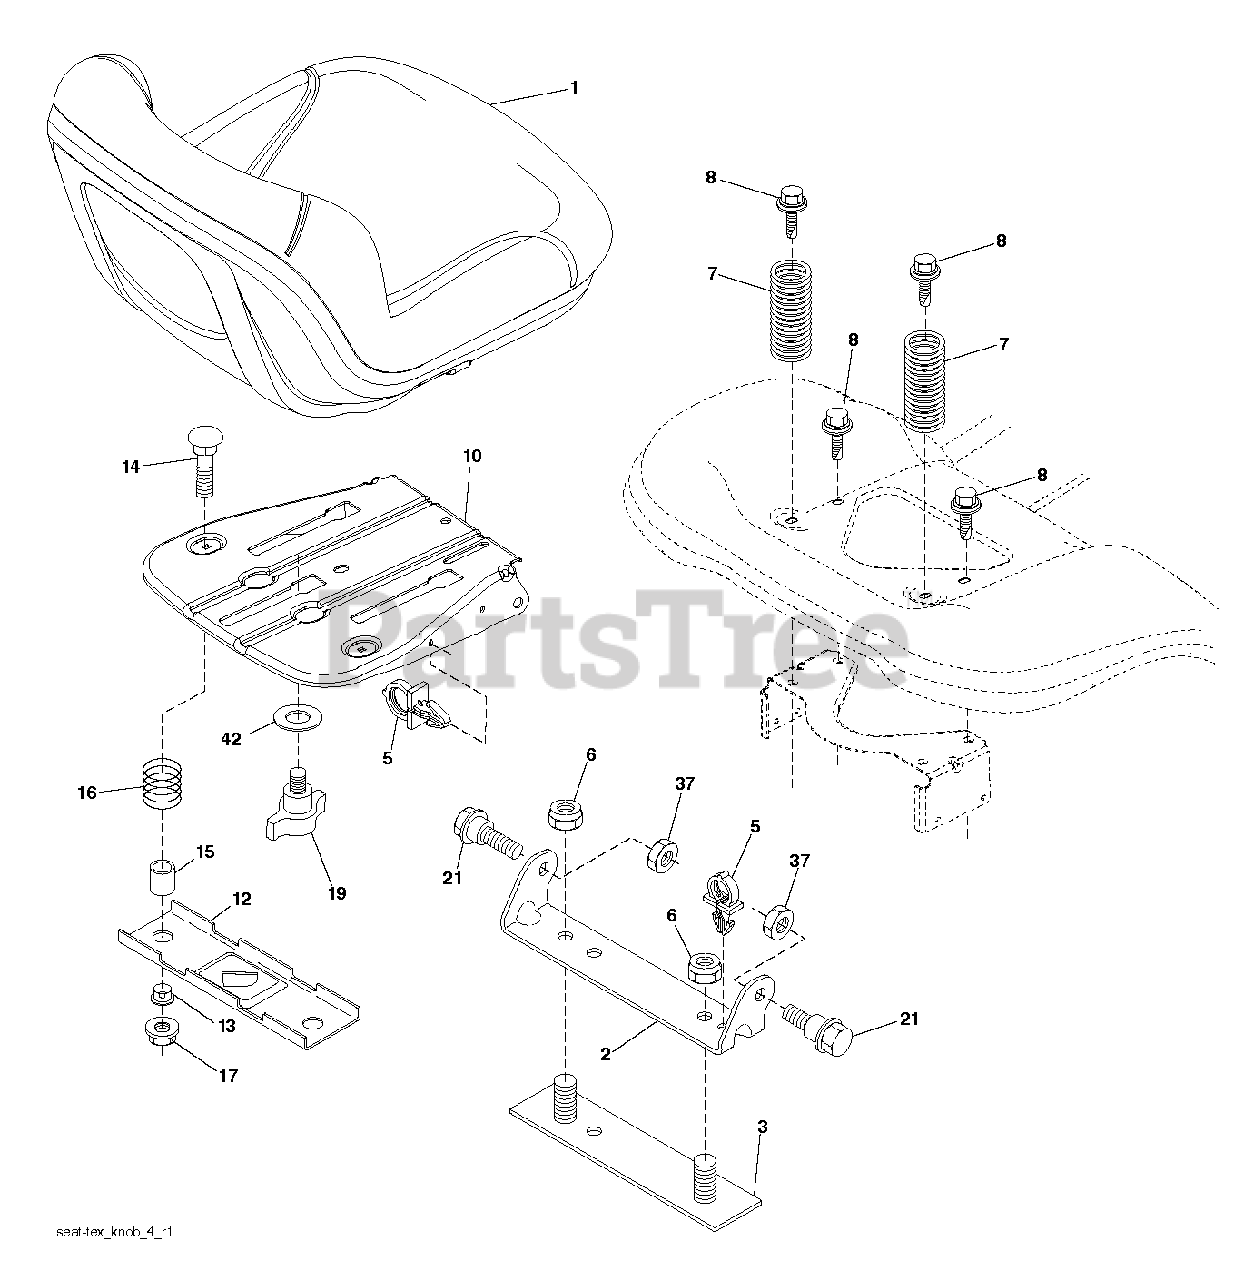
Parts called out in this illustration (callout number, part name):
1	SEAT.TP150.BLK.PPRO.KB/SL
2	BRKT.PIVOT.FENDER
5	PUSH CLIP
6	NUT
7	Compression Spring, Seat Black
8	BOLT, 5/16-18 X 1 3/4
10	PAN.ASM.SEAT.SHORT.SLD.ADJ.TEX
12	BRKT.MNT.OPC.SW.SEAT.
14	BOLT.ROUND.HEAD.SQUARE.NECK
15	SPACER SPLIT 28X.96
16	SPRING COMPRESSED
17	NUT T
19	KNOB.SEAT.ADJ.
21	Shoulder Bolt, 5/16-18 X 5/8
37	NUT.71038.31-18.HEX.NYLOCK
42	WASHER.CUP.SEAT.
